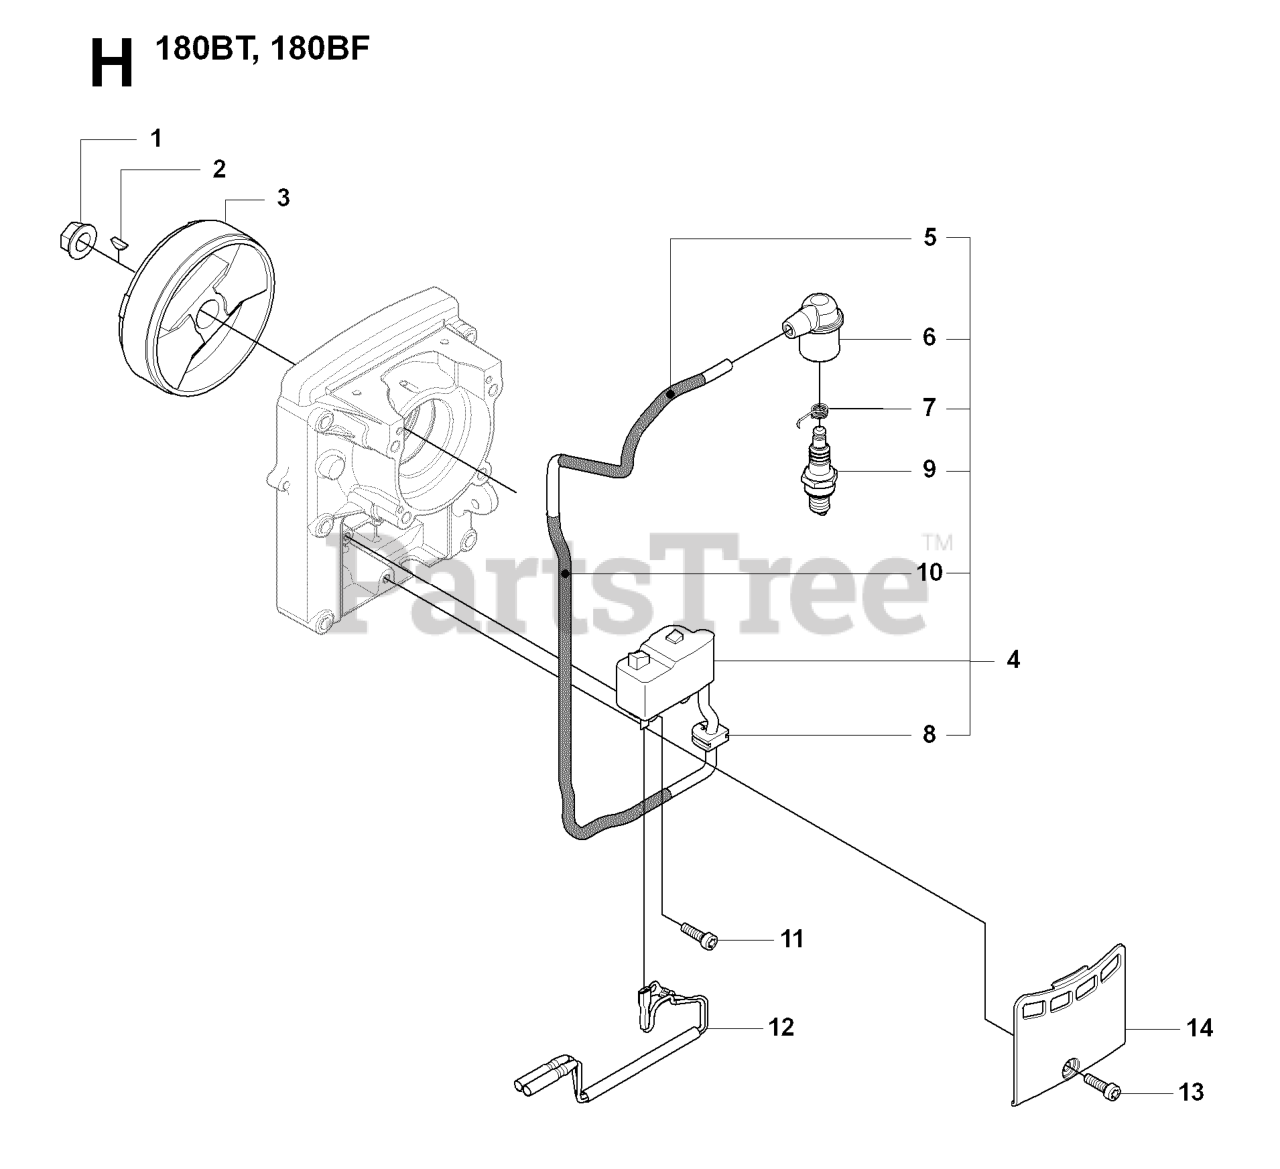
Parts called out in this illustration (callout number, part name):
1	NUT
2	KEY
4	COIL-A
6	CAP
9	SPARKPLUG NGK CMR7H
11	BOLT
13	BOLT
